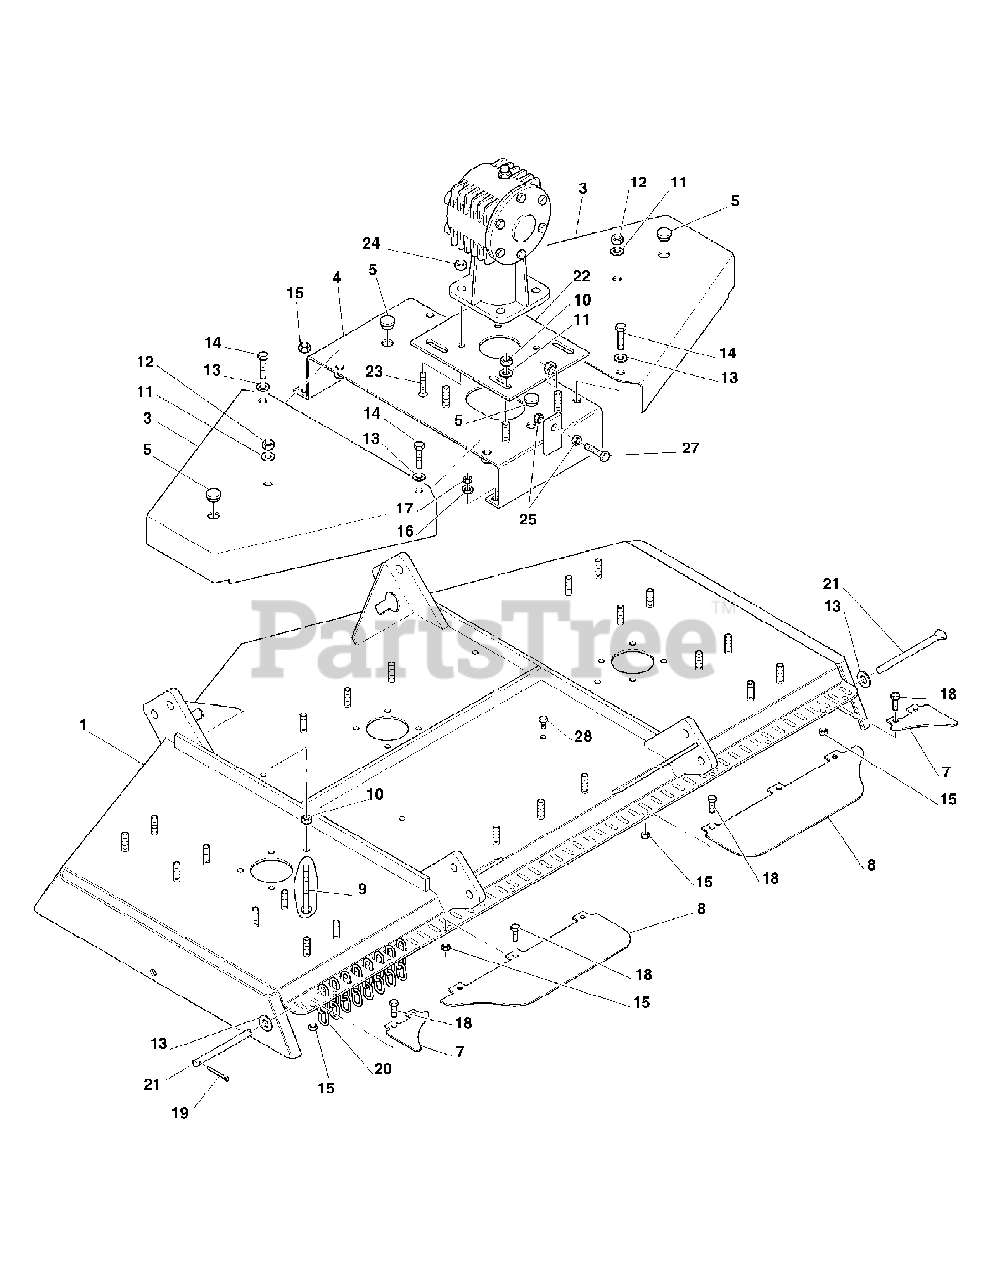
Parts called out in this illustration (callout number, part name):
1	Frame FML72
3	Belt shield FML72
4	Central plate FML72
5	Cap
7	Side rear protection FML72
8	Central rear protection
9	Bolt TE 10x120
10	Locking nut M10
11	Flat washer M10
12	Locking nut M10
13	Flat washer Ø10
14	Bolt TE 10x25
15	Nut M10
16	Lock washer Ø10
17	Nut M10
18	Bolt TE 10x20
19	Cotter pin Ø4x25
20	Chain
21	Chain rod FML72
22	Gearbox support plate
23	Bolt TSPEI 12x40
24	Nut M12
25	Nut M12
27	Bolt TE 12x100
